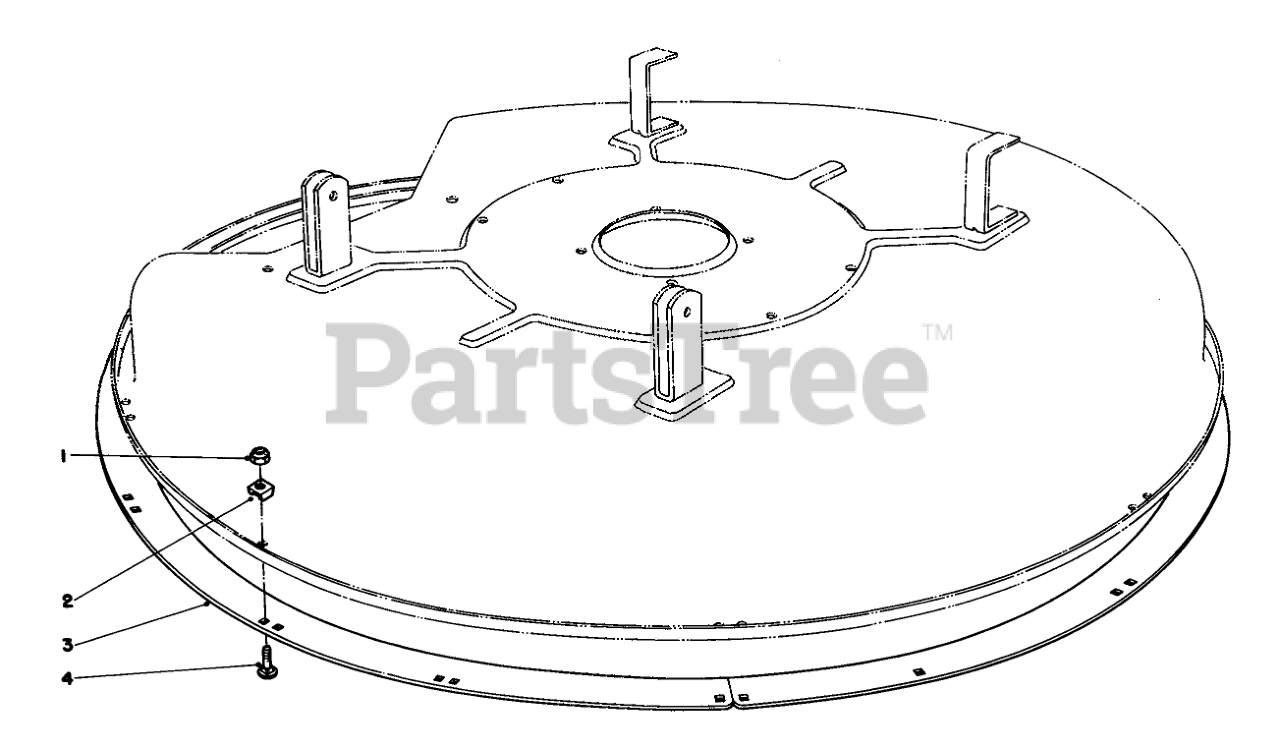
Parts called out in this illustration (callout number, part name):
1	NUT-LOCK, NI
2	DECK RING SPACER
3	DECK RING B
4	BOLT-CARR
